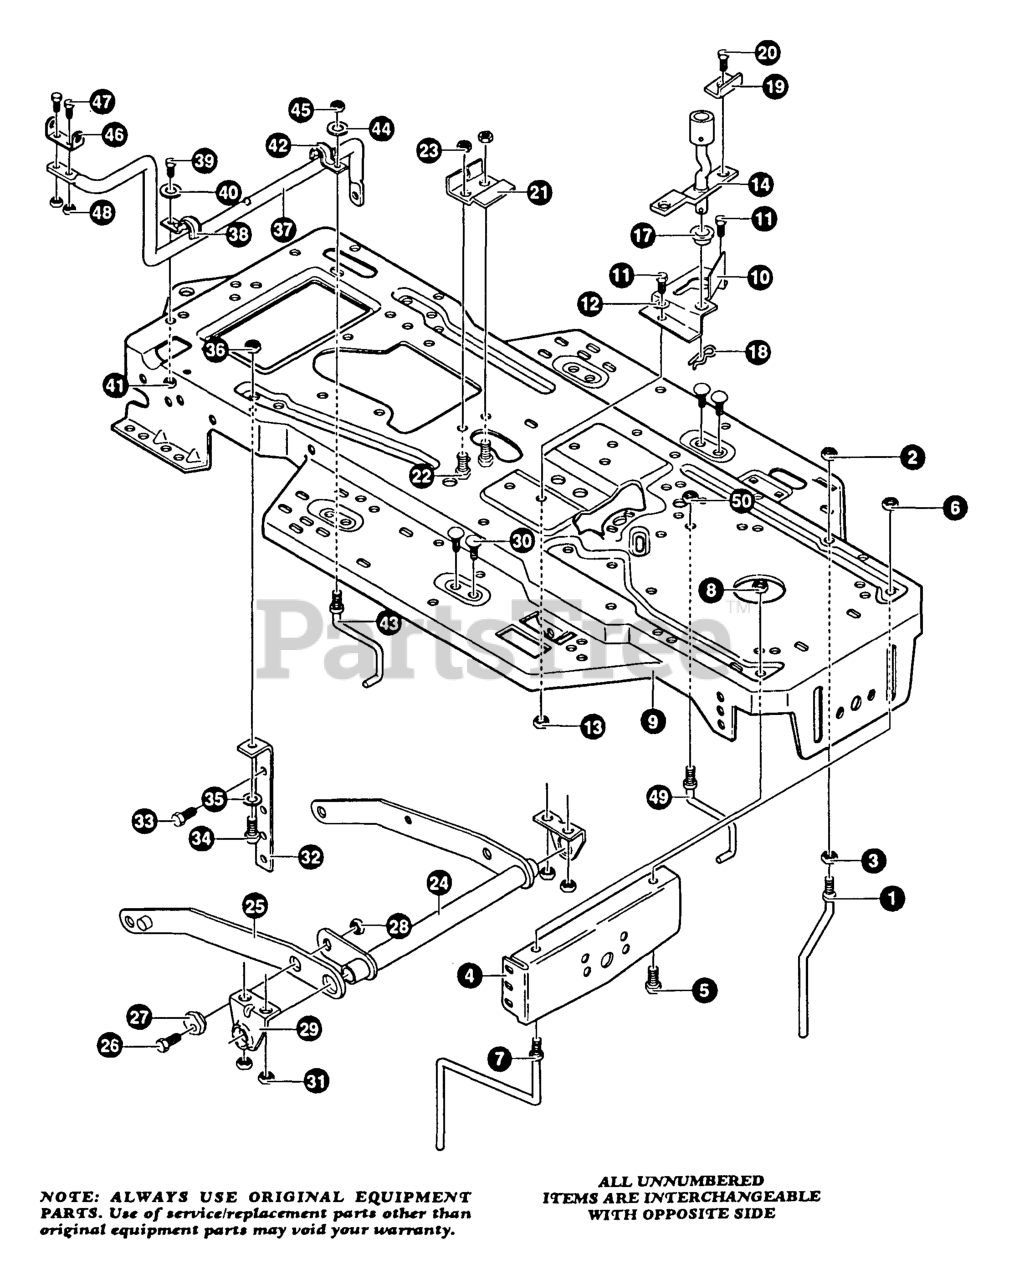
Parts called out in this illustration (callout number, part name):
1	GUIDE, BELT
4	BRKT, FRONT AXLE
5	SCREW
7	GUIDE, BELT
9	FRAME, MAIN
10	BRKT,LEVER
12	WASHER
14	ASSY, CLUTCH LEVER
17	BEARING
19	BRACKET, SWITCH
20	SCREW
21	BRACKET, CABLE
24	LIFT ASSY, LH
25	LIFT ASSY, RH
29	BRKT, REAR HANG
32	BRKT, STABILIZER
33	SCREW
35	WASHER
37	LEVER, SHIFT
38	CLIP- SHIFT LEVER
39	SCREW
40	WASHER
42	CLIP- SHIFT LEVER
43	GUIDE, BELT
44	WASHER
46	BRKT, SHIFT LEVER
49	GUIDE, BELT, RH
